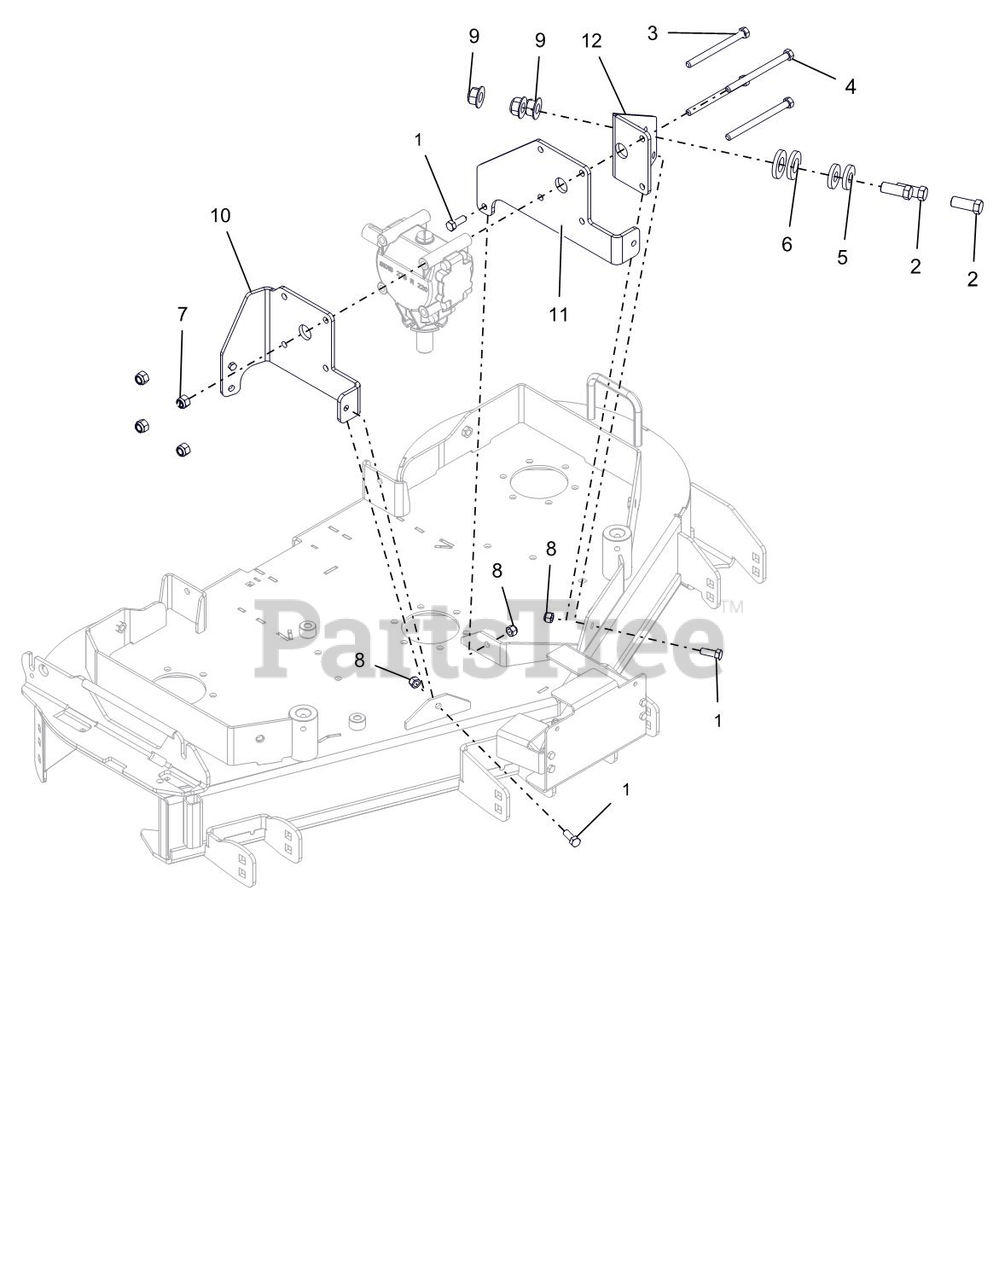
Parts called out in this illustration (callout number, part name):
1	BLT,HEX .38-16X1.00 G5 ZCC
2	BLT, HEX .62-11X1.50 G8 ZCC
3	BLT,HEX M10-1.5X120 G8.8 ZC120
4	BLT,HEX M10-1.5X130 G8.8 ZC120
5	WSHR,FLT .630X1.50X.25 ZCC
6	WSHR-FL-STL .905X1.75X.25 ZC12
7	NUT, LK-NYL M10-1.5 A2CL70 SS
8	NUT,NYL .38-16 G5 ZCC
9	NUT,NYL-FLG .63-11 GF ZCC
11	EAR, LH-INSIDE
12	EAR, LH-OUTSIDE
